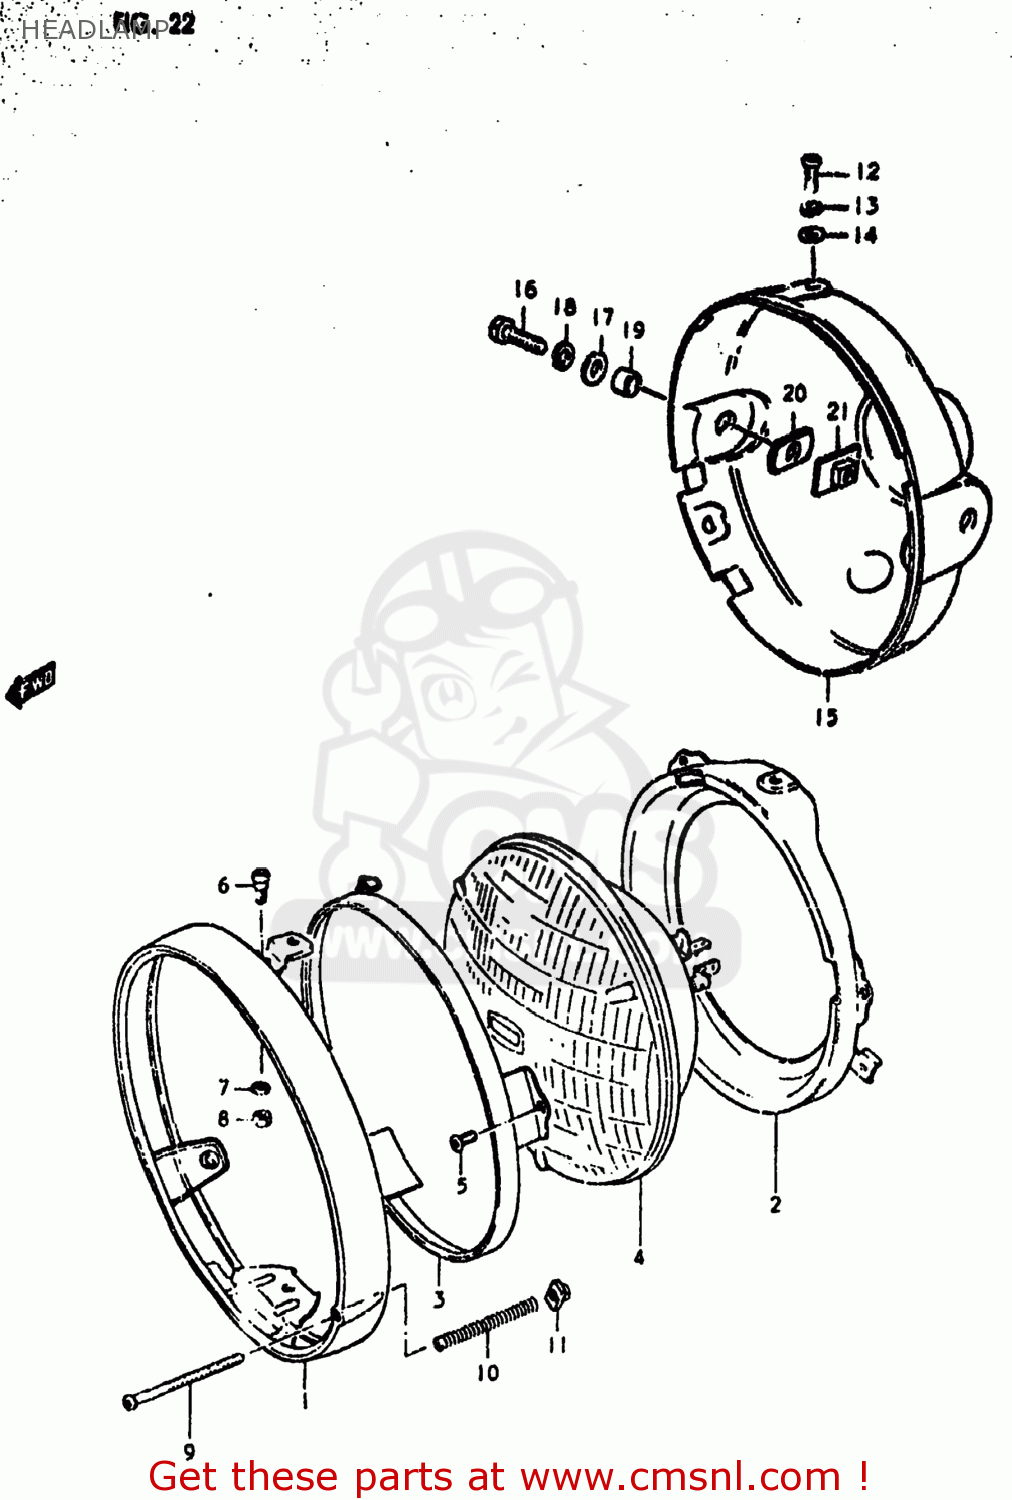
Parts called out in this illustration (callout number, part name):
1	RIM
2	RING
3	RETAINING RING
4	UNIT,HEADLAMP
5	SCREW
6	H/LAMP LENS UNIT FITING SCRE
7	LOCK WASHER
8	NUT M4 DIN 985
9	SCREW,HEADLAMP ADJUST
10	SPRING,ADJUSTING
11	NUT
12	SCREW
13	WASHER,LOCK
14	WASHER
15	HOUSING,HEADLAMP(BLACK)
16	BOLT
17	WASHER
18	LOCK WASHER
19	SPACER (8.8X12X7)
20	CUSHION
21	PLATE,HEADLAMP HOUSING
